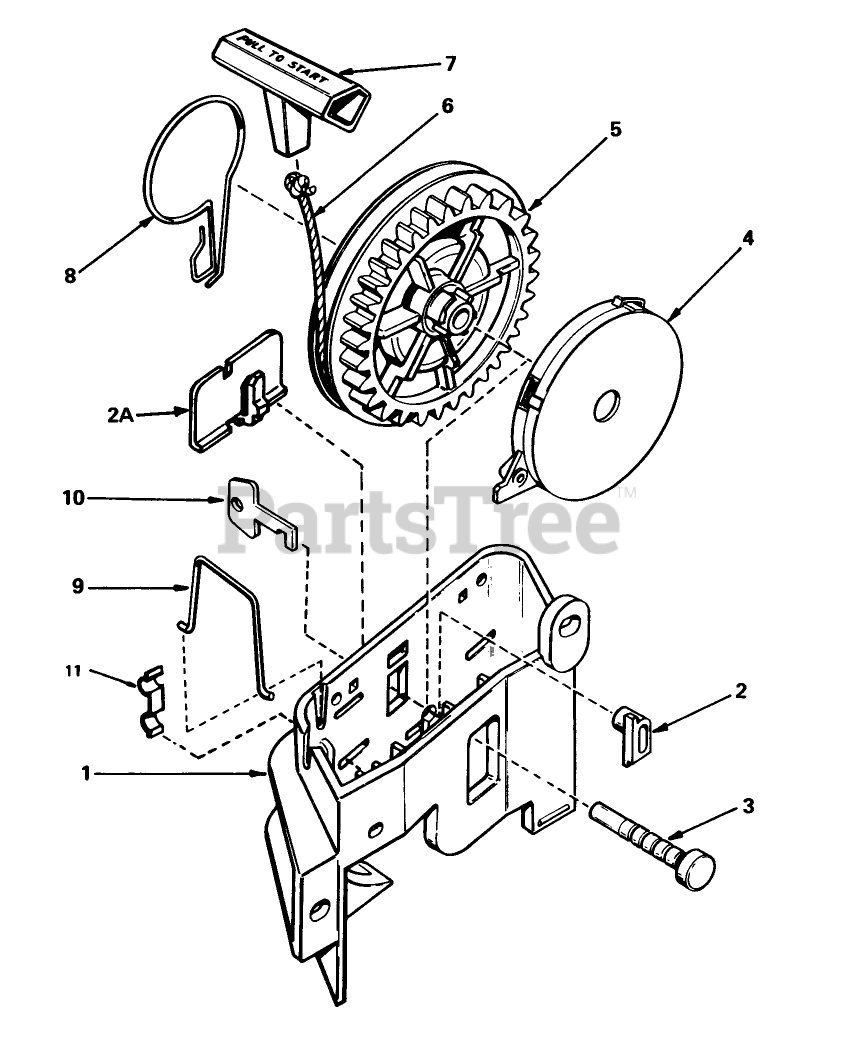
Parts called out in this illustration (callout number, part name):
1	Bracket Starter
2	Pawl, Locking Not used on all engine models)
2A	Clip, Starter Bracket (Used On Starters Not Equipped With Pawl, Ref. No. 2)
3	Pin-Pulley
4	Spring Assy., Rewind (Incl. Ref. #3)
5	Pulley
6	Rope-Starter (98 cut to length)
7	Handle-Starter
8	Brake
9	Clip-Rope
10	Key (Not Used On All Engine Models
11	Clip-Bowden Wire (Not used on all engine models)
